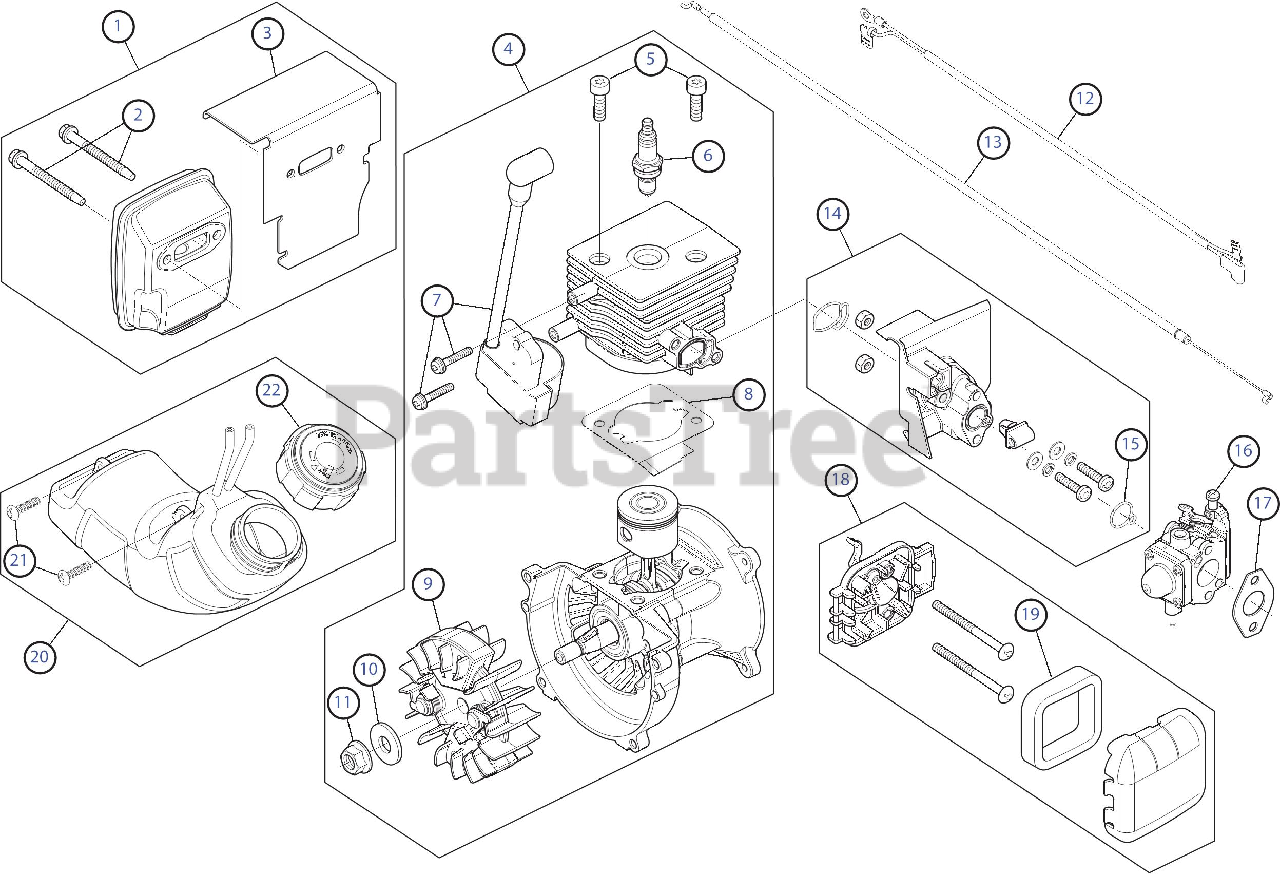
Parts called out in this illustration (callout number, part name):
1	Muffler Assembly (Incl. 2 & 3)
2	Muffler Screws
3	Muffler Gasket
4	Shortblock Assembly (Incl. 5 - 11)
6	Spark Plug
7	Module Assembly
8	Cylinder Gasket
9	Flywheel Assembly
10	Washer
12	Lead Wire
13	Throttle Cable
14	Insulator Assembly (Incl. 15)
15	Insulator O-Ring
16	Carburetor Assembly (Incl. 17)
17	Carburetor Gasket
18	Air Cleaner Assembly (Incl. 19)
19	Air Filter
20	Fuel Tank Assembly (Incl. 21 & 22)
22	Fuel Cap
